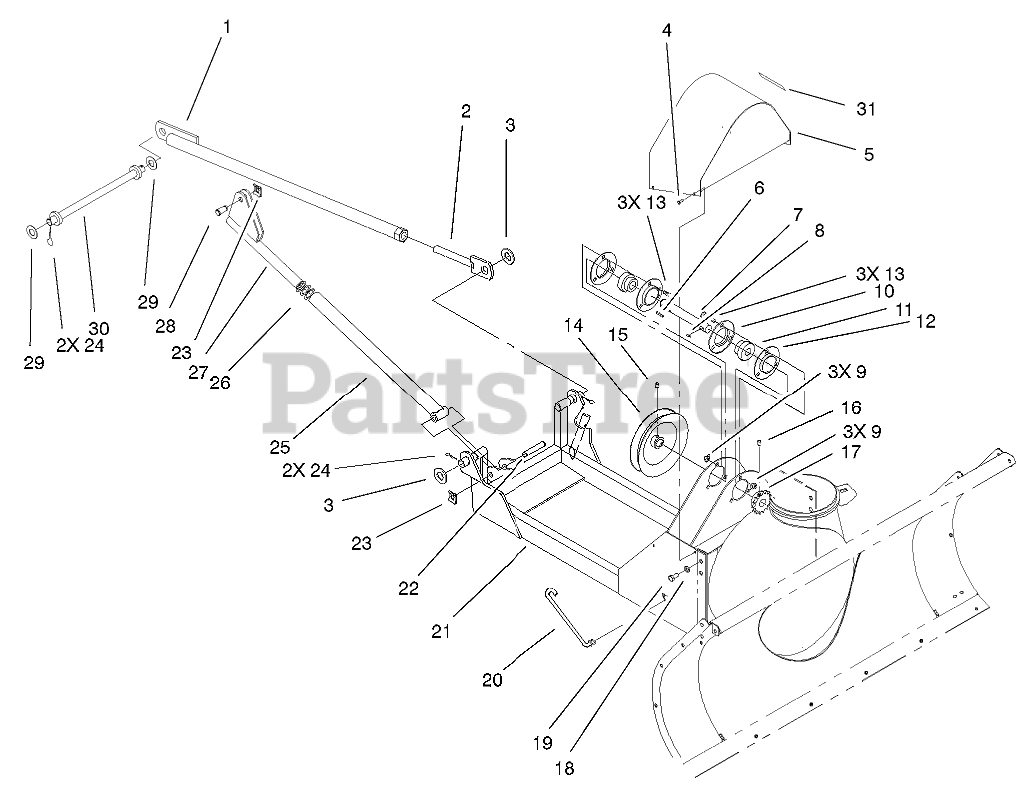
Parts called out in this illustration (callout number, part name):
1	BRACE ASM
2	ADJUSTER ASM
3	WASHER-FLAT
4	SCREW-TAPTITE
5	PULLEY COVER ASM
6	KEY
7	SHAFT - JACK
8	KEY-HI PRO
9	NUT-LOCK, NI
10	FLANGE-RELUBE
11	BEARING AND COLLAR
12	Flange
13	BOLT-CARR
14	PULLEY-DRIVE
15	SCREW-SQH
16	SCREW-SET
17	SPROCKET-15T
18	WASHER-LOCK
19	SCREW-HH
20	LINK-SPRING TENSION
21	FRAME ASM
22	PIN-CLEVIS
23	CLIP-PIN
24	PIN-COTTER, HAIR
25	ROD-LIFT
26	WASHER-FLAT
28	PIN-CLEVIS
29	WASHER-FLAT
30	LINK ASM
31	DECAL-IMPORTANT
